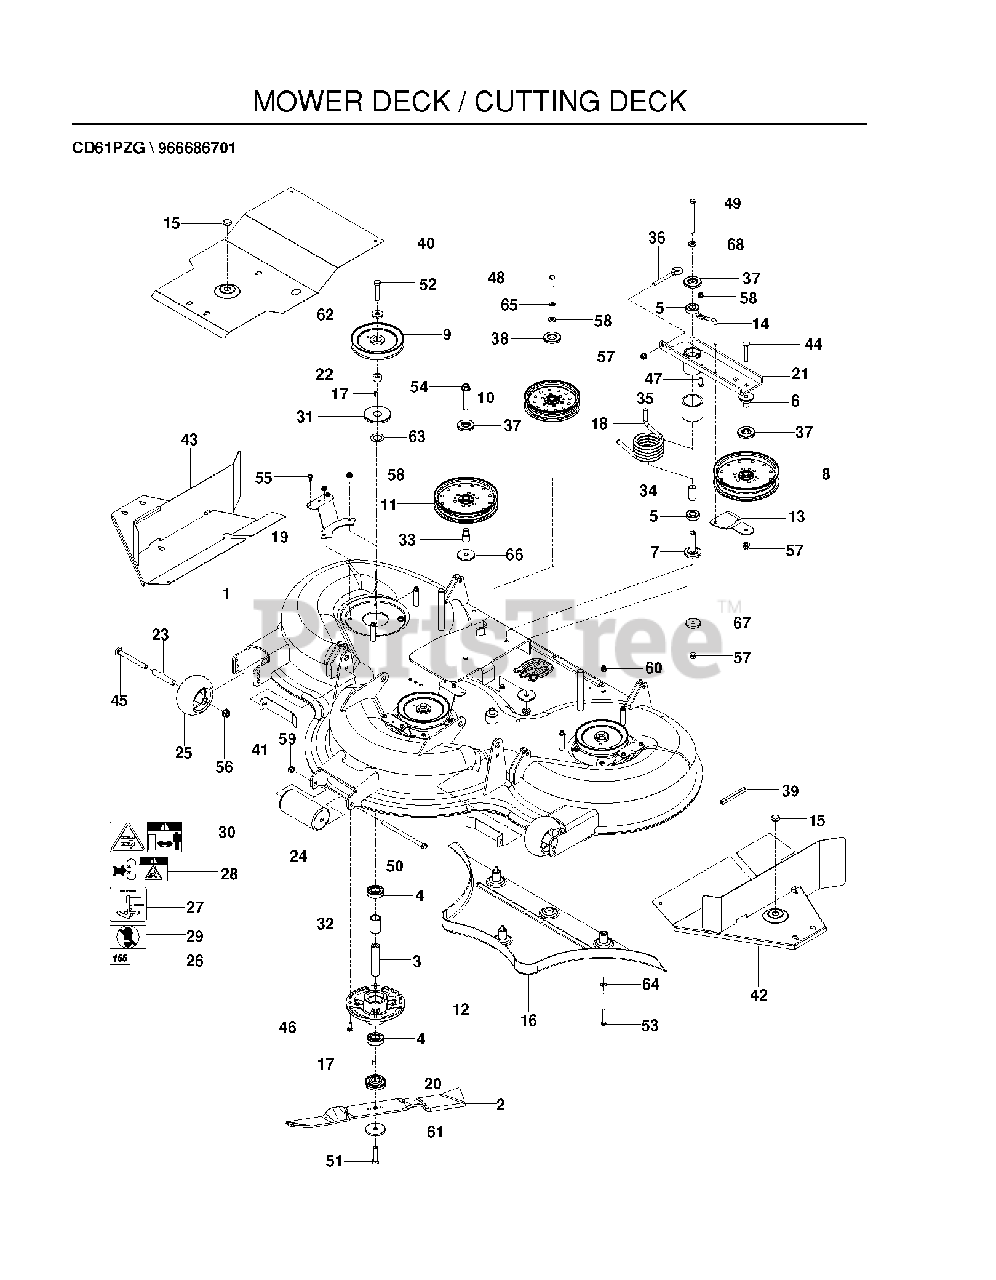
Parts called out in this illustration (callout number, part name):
1	DECK W/SAFETY DECALS
4	BALL BEARING
5	BEARING, BALL
6	BEARING, IDLER ARM
7	BEARING, IDLER PIVOT
8	PULLEY - IDLER 7"
9	PULLEY, 61
10	PULLEY IDLER, 6" NARROW
11	PULLEY - 7" NARROW
12	BEARING HOUSING
13	BELT.GUIDE.BLACK
14	BELT KEEPER
15	PLUG, BUTTON HOLE
16	PLUG ASSEMBLY
18	SPRING, TORSION, IDLER
19	BRACKET,BELT CVR,COMBI BLK
20	BUSHING, BLADE
21	IDLER.ARM.BLACK
22	KEY RETAINER
23	TUBE, ROLLER AXLE
24	ROLLER
25	ROLLER, GAUGE .635 BORN
26	Decal, 155
27	DECAL, BELT ROUTING
28	DECAL, BELT DRIVE
29	DECAL, NO STEP
30	DECAL, EURO SEVERING
31	TOP DUST CAP
33	SPACER - IDLER
34	SPACER, IDLER BEARINGS
35	SPACER, IDLER PIVOT
36	EYE BOLT, 3/8 X 4"
37	DUST SHIELD
38	SHIELD, DUST
39	FLEX TRIM, BLACK - LENGTH 1 FT
40	GUARD.CENTER.COMBI.61.BLACK
41	GUARD, COMBI STRUT, BLK
42	WLDMNT, LEFT COMBI 61, BLK
43	WLDMNT, RIGHT COMBI 61, BLK
44	CARRIAGE BOLT 3/8-16 X
45	RHSNB 1/2-13 X 4.75 GR5 ZD
46	RHSNB 5/16C X 1
47	RHSSNB 5/16C X 1.0
48	HCS 3/8C X 1 1/4 GR5
49	HCS 3/8F X SPECIAL
50	HCS 7/16-14 X 7 GR5 ZD
51	HCS M12 X 1.75 X 50 GR8.8 ZD
52	HCS M12 X 1.75 X 60 GR5 ZD
53	HCS M8 X 1.25 X 50 GR8.8 ZD
54	HFFS 1/2-13 X 3 GD 5 ZD
55	SCREW- 1/4-20 X 5/8
56	NUT, 1/2-13 HEX FLG NYLOC ZD
57	NUT 3/8-16 HEX FLG NYLOC ZD
58	5/16-18 NYLOC FLANGE NUT
59	NUT 7/16C CENTERLOCK
60	BLIND RIVET NUT
62	WASHER-.533IDX1.37OD
63	WASHER-1.06IDX1.63ODX.06
64	FLAT WASHER 5/16 SAE
65	SLW 3/8 STD
66	WASHER, HEAVY
67	SPINDLE WASHER
68	WASHER, 3/8 THICK
